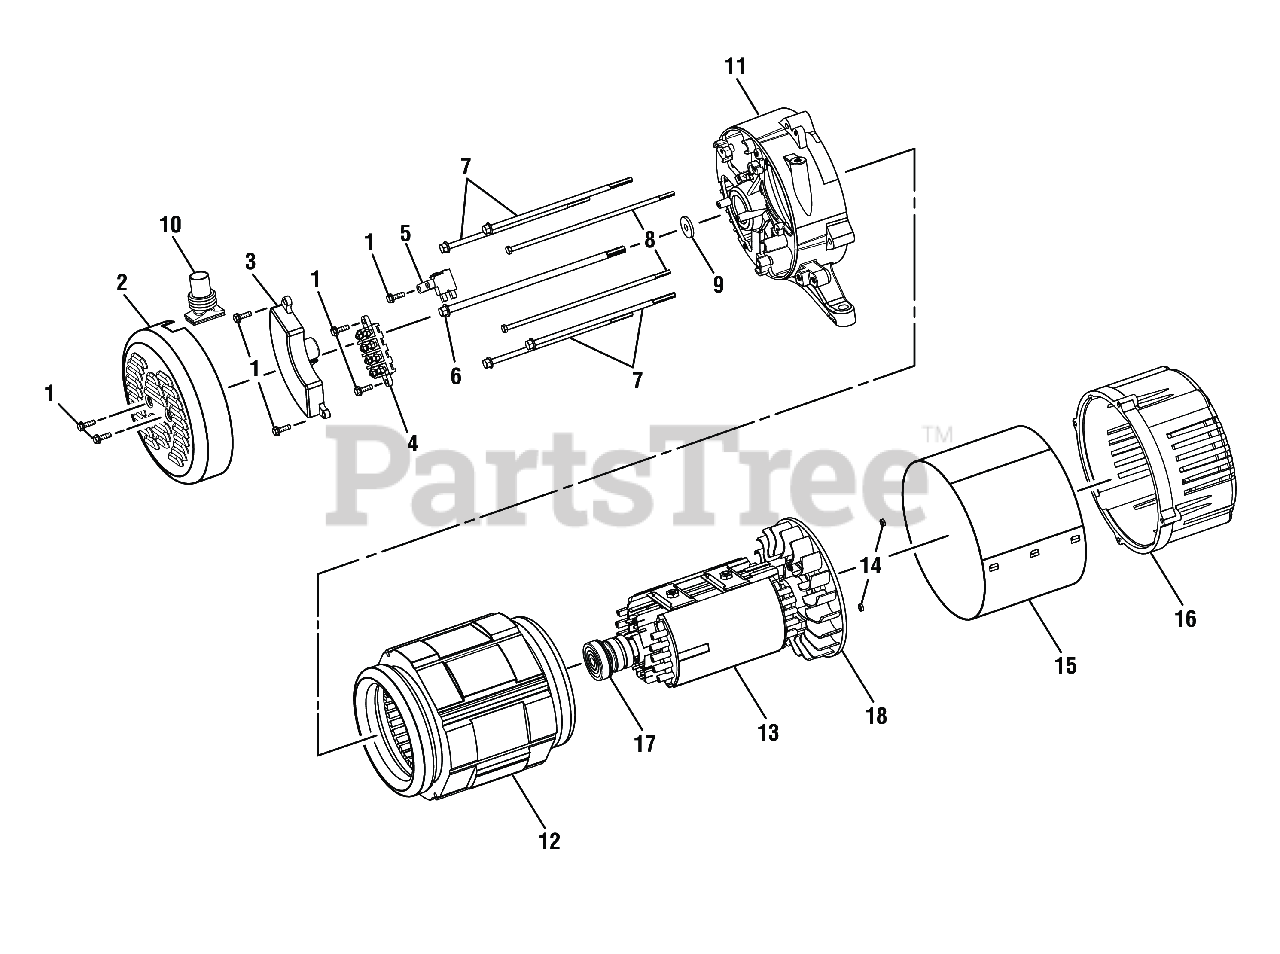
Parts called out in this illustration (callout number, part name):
1	Bolt (M5 x 170 mm, Hex Washer Hd.)
2	Brush Cover
3	Automatic Voltage Regulator (5000 Watt)
4	Terminal Block
5	Brush Assembly 190 mm
6	Bolt (5/16-24 x 235 mm, Hex Washer Hd.)
7	Bolt (M6 x 188 mm, Hex Washer Hd.)
8	Bolt (M5 x 210 mm, Hex Washer Hd.)
9	Washer (ID10.5 x OD25 x 2t)
10	Rubber Boot
11	Bearing Housing'
12	Stator Assembly
13	Rotor Assembly
14	Hex Nut (M5)
15	Generator Head Cover
16	Generator Head Cover
17	Ball Bearing (190 mm)
18	Fan (190 mm)
